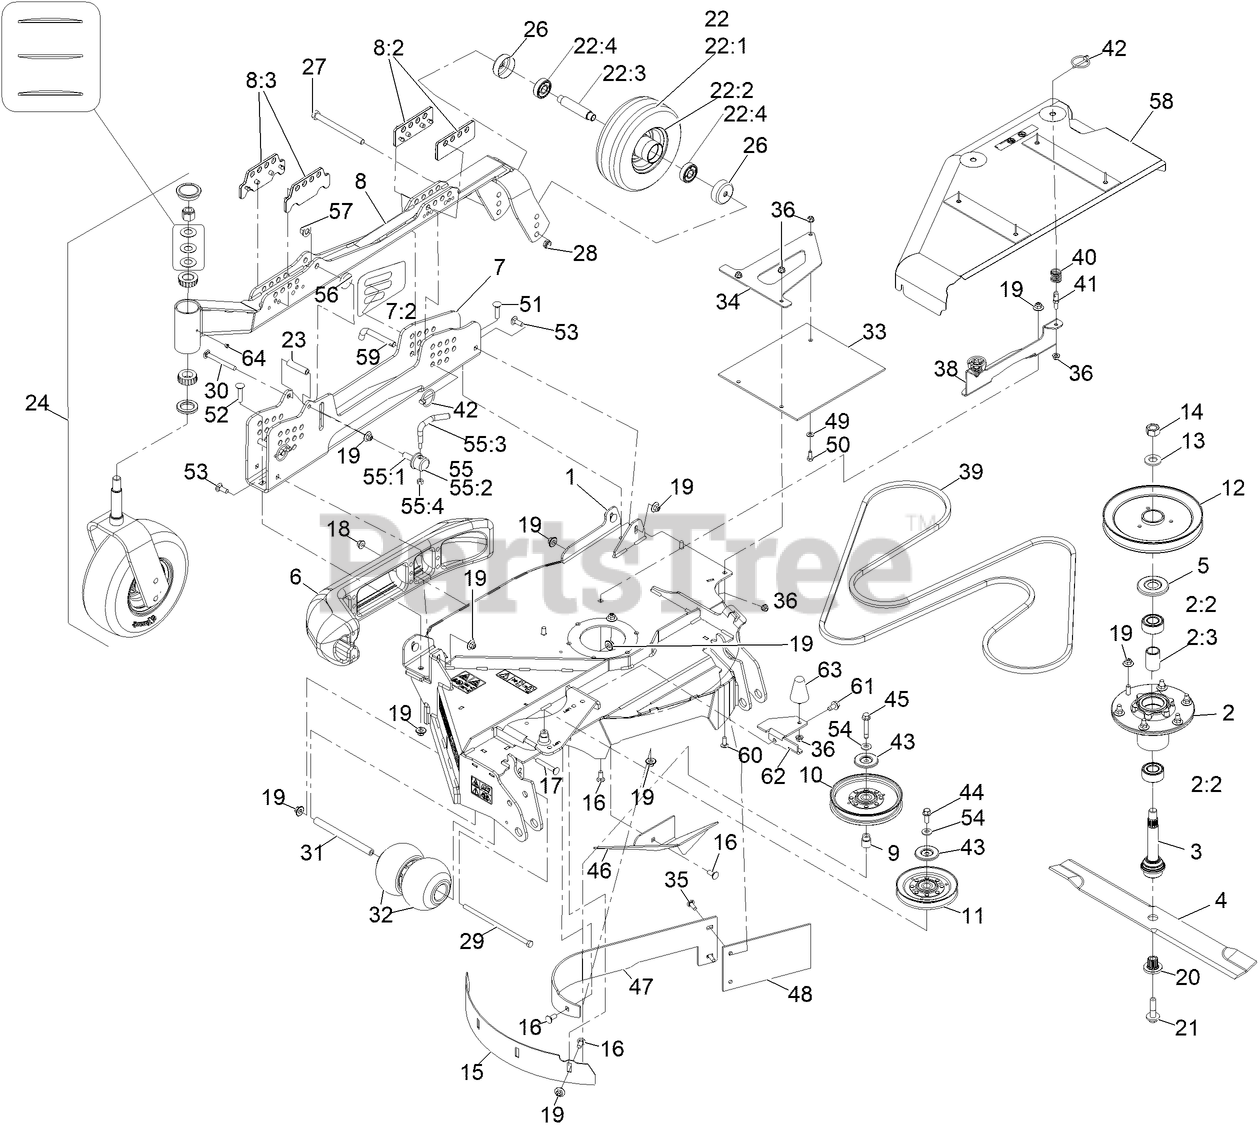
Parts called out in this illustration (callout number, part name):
1	ASM-Deck, RH Wing 96
2	ASM-CUTTER HSG
2:2	BEARING-3205 TRASHGUARD
2:3	SPACER-BEARING
3	ASM-SPINDLE AND SEAL
5	GUARD-BEARING, TOP
6	SKID-BUMPER, DECK
7	ASM-CHANNEL, HOC RH W/DECALS
7:2	DECAL-HEIGHT OF CUT, RH
8	ASM-RH GAUGE WHEEL ARM
8:2	PLATE-GUIDE, REAR
8:3	PLATE-GUIDE, FRONT
9	BUSHING-IDLER
10	IDLER-PULLEY
11	IDLER-V
12	SHEAVE-SINGLE 96RD
14	NUT-HEX
15	BAFFLE-DEPTH, RH
16	BOLT-CARR
17	SCREW-CARR
18	NUT-HF, NI
19	Nut-Nyloc 3/8-16 Flg
20	BUSHING,SPLINED
21	SCREW,SEMS 1/2-20 X 2.19
22	WHEEL AND TIRE ASM
22:1	Wheel-4 X 2.25 X 4.41 Tube
22:3	AXLE-CASTER
22:4	BEARING
26	GUARD, SEAL
27	SCREW-HH
28	NUT-HEX
29	SCREW-HH
30	SCREW-CARR
31	SPACER-WHEEL
32	ROLLER-SCALP, ANTI
33	GUARD-TIRE
34	SUPPORT-FLAP, RH
35	SCREW-CARR
36	NUT-HF, NI
38	BRACKET-SHIELD MOUNT, OUT
41	PIN, SPRING
42	PIN-LYNCH
43	SHIELD-DUST
44	SCREW-HHF 3/8-16 X 1
45	SCREW-HHF
46	BAFFLE-DEFLECT, RH
47	BAFFLE-DOGLEG, RH
48	FLAP-RUBBER
49	WASHER-PLAIN
50	SCREW-HH
51	SCREW-CARR
52	SCREW-CARR
53	BOLT-CARR
54	WASHER-BELLEVILLE
55	LEVER ASM
55:1	SCREW-LOCK
55:2	CAP-LOCK
55:4	NUT-LOCK, NI
57	Nut-Lock 1/2-13
58	ASM-Wing Shield RH
59	PIN-HOC
60	BOLT-CARR
61	SCREW-HWH
62	BRACKET-COVER RETAINER
63	BUMPER-RUBBER
